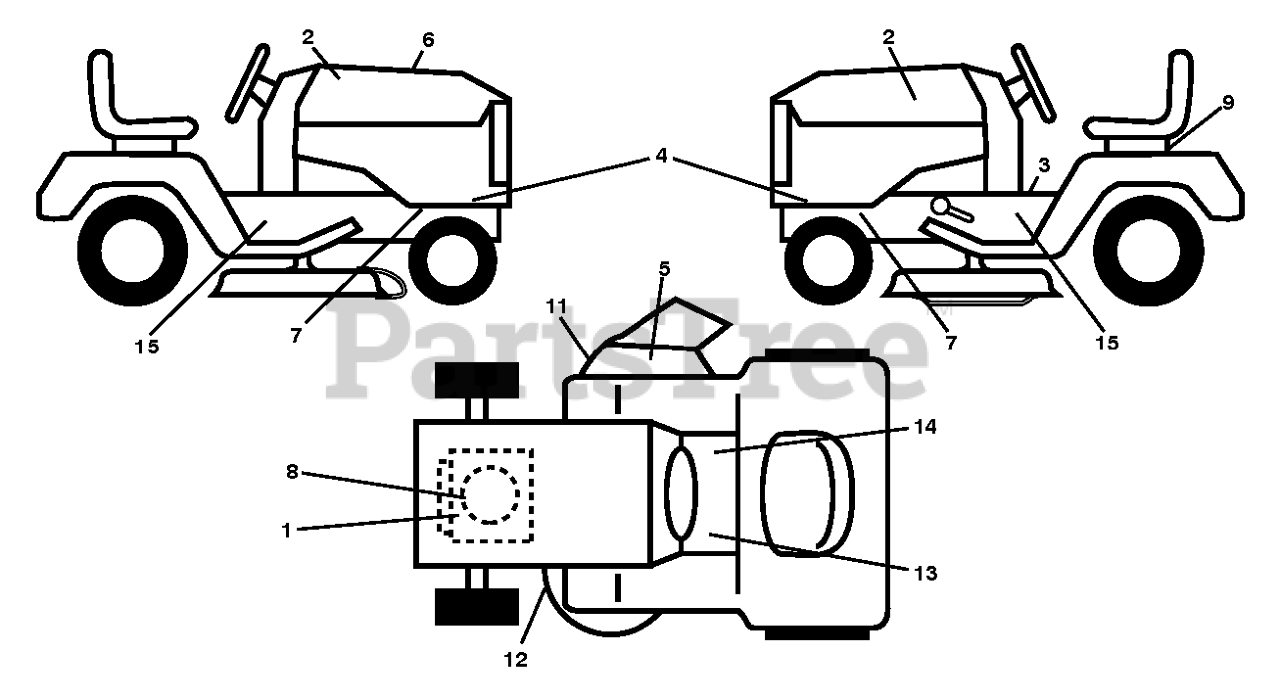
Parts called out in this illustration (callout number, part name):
1	DECAL.ENGINE.WARNING
2	DECAL.BADGE.170MM.TEXTLOGO.
3	DECAL.READ.OWN.MAN.SYMBOL.LT
7	DECAL.CHASSIS.HOT.MUFFLER
8	DECAL
9	DECAL BTRY SYMBOLS
11	DECAL.WARN.DFLCTR/CTFNGR.SRD.
12	DECAL.V.BELT.30"
13	DECAL.FNDR.SDLE.BRAKE.CLUTCH.6
14	DECAL.PARKING.BRAKE.SADDLE.LT
15	DECAL.WARNING.SERVCE/FIRE
